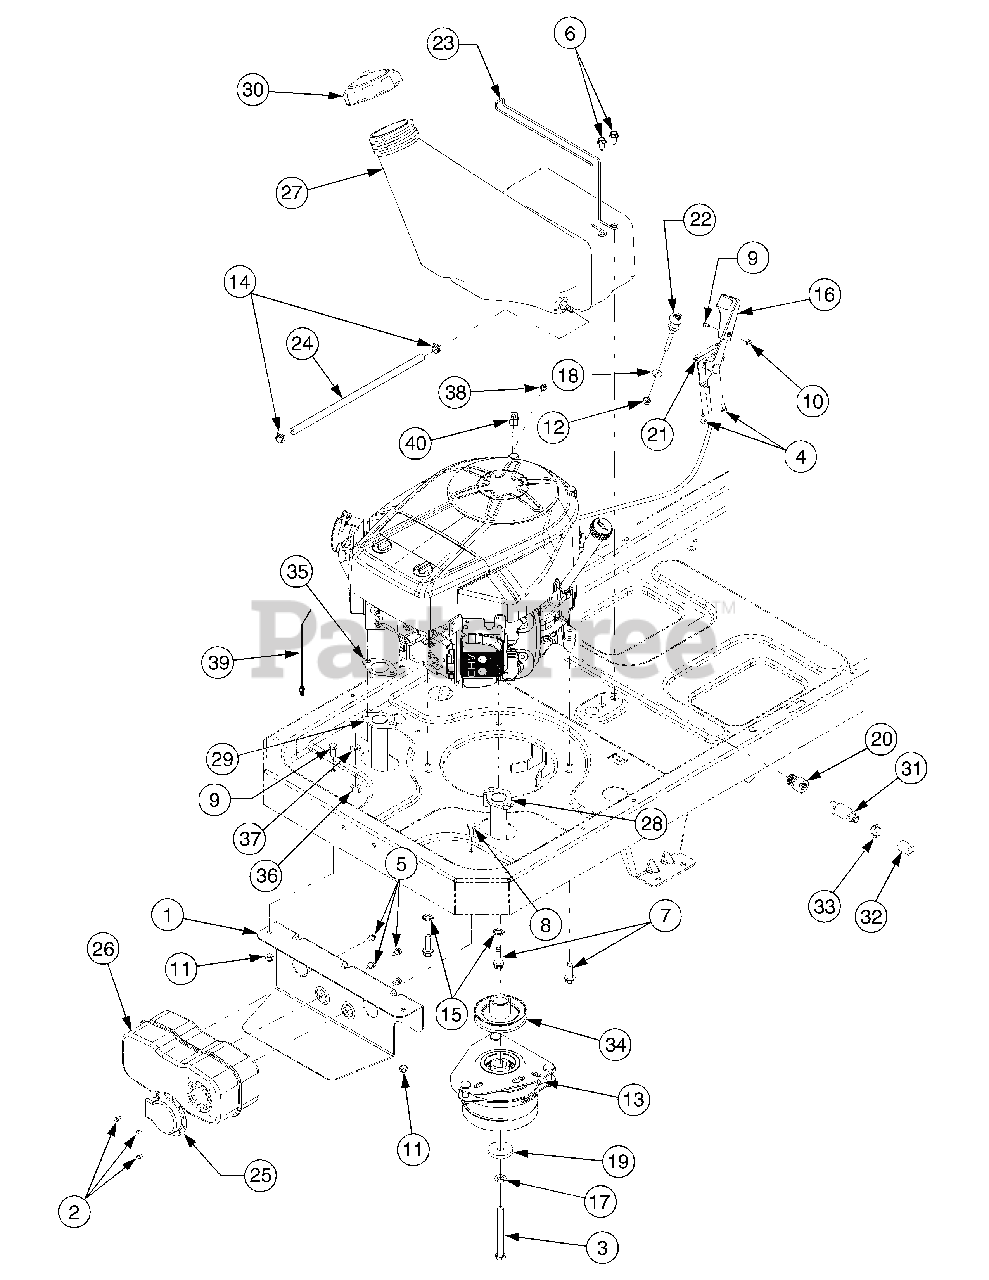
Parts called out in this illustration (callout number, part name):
1	Bracket, Muffler Mounting
2	Screw, Hex Wash. Hd. Tapp #8-18 x .5
3	Screw, Hex Cap, 7/16-20 x 4.0 GR5
4	Screw, Hex Wash. Hd. Tapp #12-16 x .5
5	Screw, Hex Wash. Hd. Tapp 1/4-20 x .5
6	Screw, Hex Wash. Hd. Tapp 5/16-12 x .75
7	Screw, Hex Wash. Hd. Tapp 3/8-16 x 1.25
8	Screw, Hex Cap, 5/16-18 x .75 GR5
9	Screw, Truss Hd. Mach. #8-32 x .375
10	Nut, Hex, #8-32
11	Nut, Hex Insert Lock, 5/16-18 GR5
12	Nut, Hex Jam, 3/8-16 GR2
13	Clutch Assembly, Electric PTO
14	Clamp, Hose
15	Washer, Ext. Tooth Lock, 3/8
16	Knob, Throttle Control
17	Washer, Lock, 7/16
18	Washer, Flat, .406 x .875 x .059
19	Washer, Flat, .438 x 1.75 x .25
20	Fitting, Hex
21	Cable, Throttle, 34.25 Lg
22	Cable, Choke, 61Lg
23	Wire, Tank Mounting
24	Hose, Fuel Line
25	Deflector, Muffler
26	Muffler
27	Tank, Fuel, 3.0 Gal.
28	Pipe, Exhaust RH
29	Pipe, Exhaust LH
30	Cap, Fuel
31	Drain, Oil
32	Hose, Oil Drain Extension
33	Cap,.Oil Drain
34	Pulley, Drive
35	Gasket, Muffler
37	Washer, Lock
38	Nut, Sems, 1/4-20
39	Tie, Push Mount Cable
